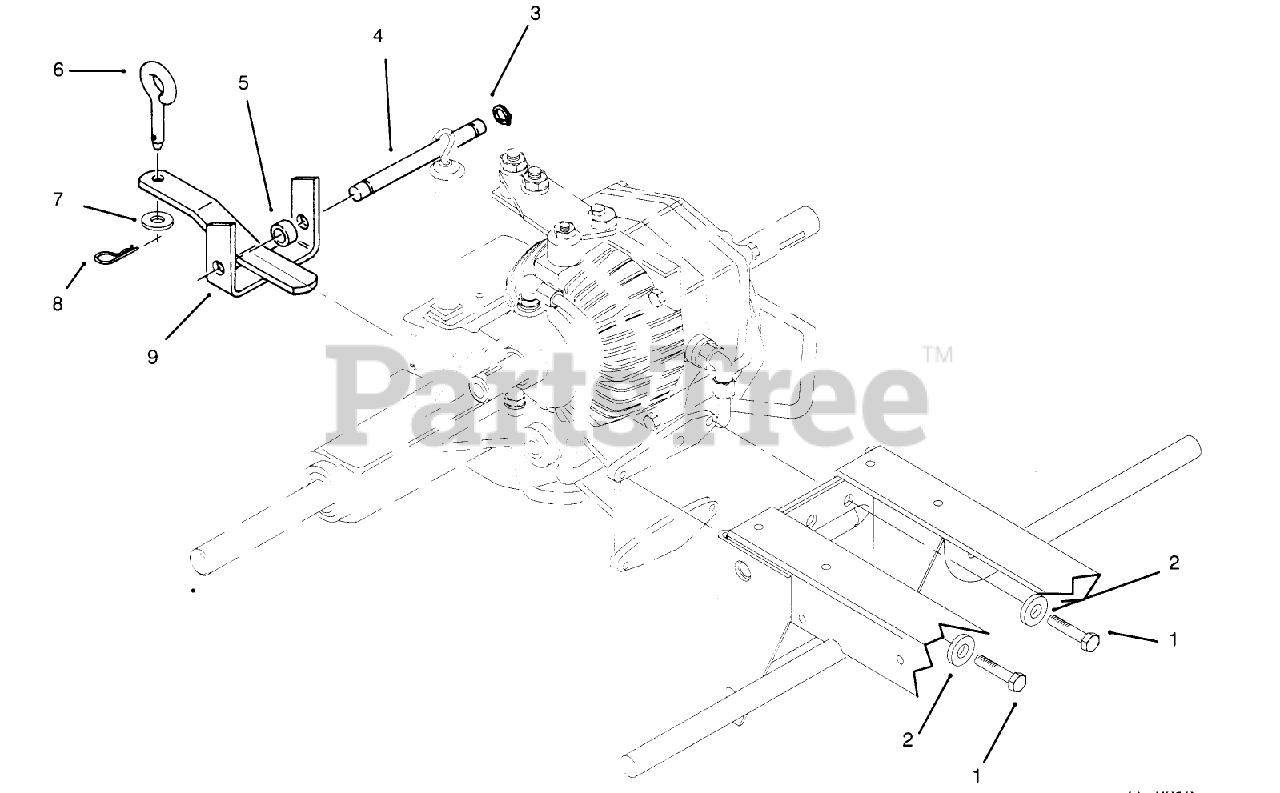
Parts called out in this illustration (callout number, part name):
1	SCREW-HH
2	WASHER-LOCK
3	E-RING
4	PIN-STATIONARY HITCH
6	PIN-TOOL
7	WASHER-FLAT
8	Hairpin Cotter
